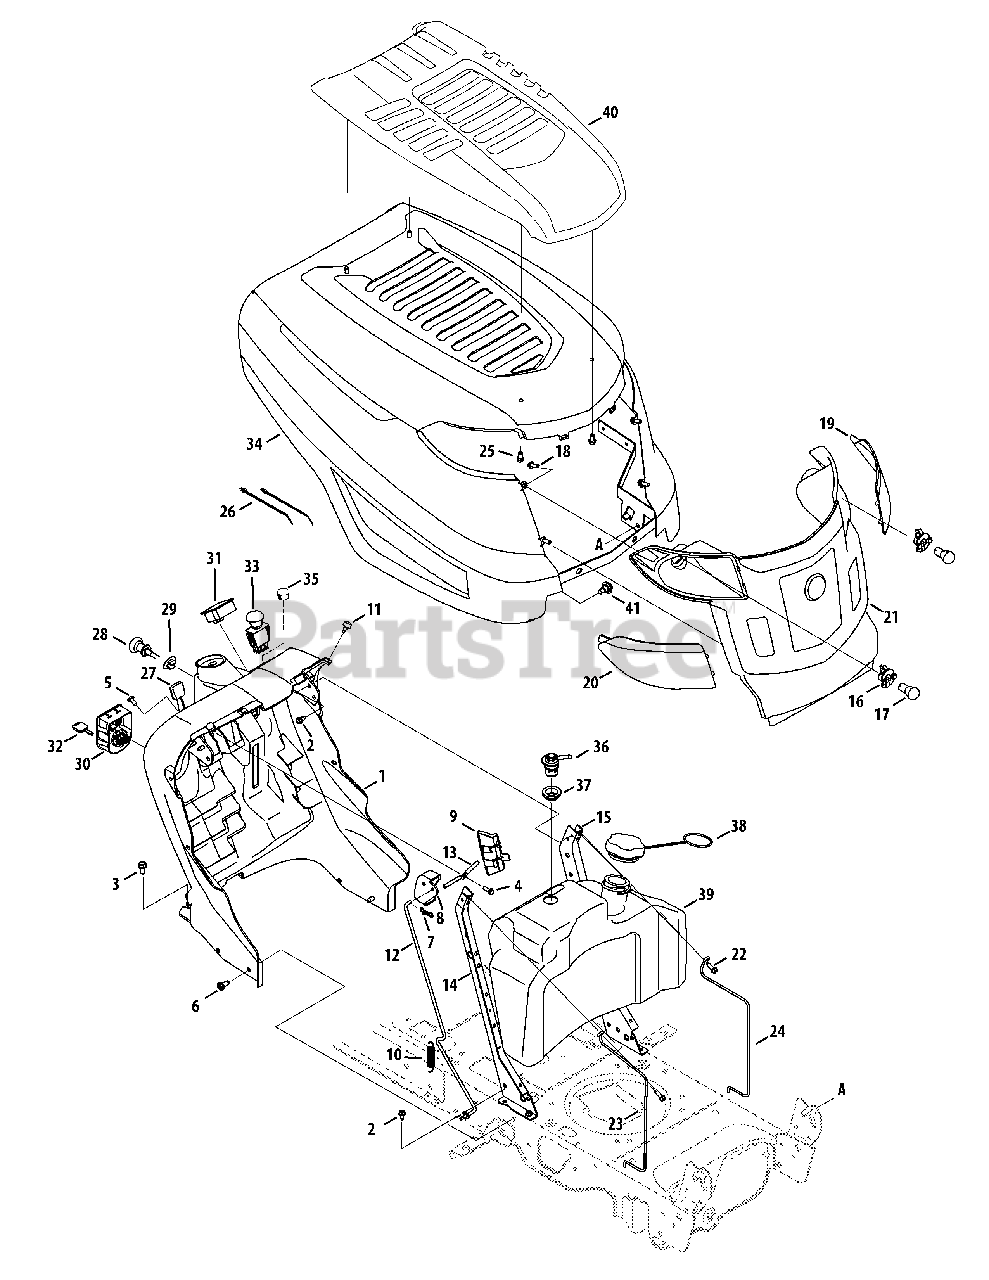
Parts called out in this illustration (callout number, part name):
1	Dash Panel (Elect PTO)
2	Screw, 1/4-20 x .50
3	SCREW 5/16-18 x .750
4	Hex Tapp Scr 1/4 x .75" Lg.
5	Torx Mach. AB-Tapp Scr. 1/4-14 x .625 Lg
6	Screw 5/16-18 x .75
7	Bow Tie Cotter Pin
8	Dash Lever
9	Cruise Cover
10	Extension Spring .500 Dia. x 2.733" Lg.
11	Bumper
12	Control Rod
13	Pivot Rod
14	RH Dash Support Plate
15	LH Dash Support Plate
16	Lamp Socket
18	Screw 1/4 x .75
19	Lens LH
20	Lens RH
21	Grille Style "K"
22	TT Scr. 1/4-20 x .625 Lg.
23	LH Support Rod
24	RH Support Rod
25	Hex Screw 1/4-15 x .50
26	Cable Tie
27	Throttle/Choke Cont. Cable (Kohler Twin)(w/Electric PTO)
28	Choke Cable (Kohler Twin)
29	Choke Plug (Single Cyl.)
30	Module Ignition Switch
31	Systems Ind. Monitor w/Hr. Meter
33	Electric PTO Switch (Electic PTO Only)
34	HOOD ASSEMBLY(K STYLE) (OYSTER GRAY)
36	Rollover Valve
37	Rubber Grommet
38	Cap-Fuel (w/hoop)
39	Tank Ass'y
40	Hood Scoop
41	Shoulder Screw 5/16-18: .43 x .29
